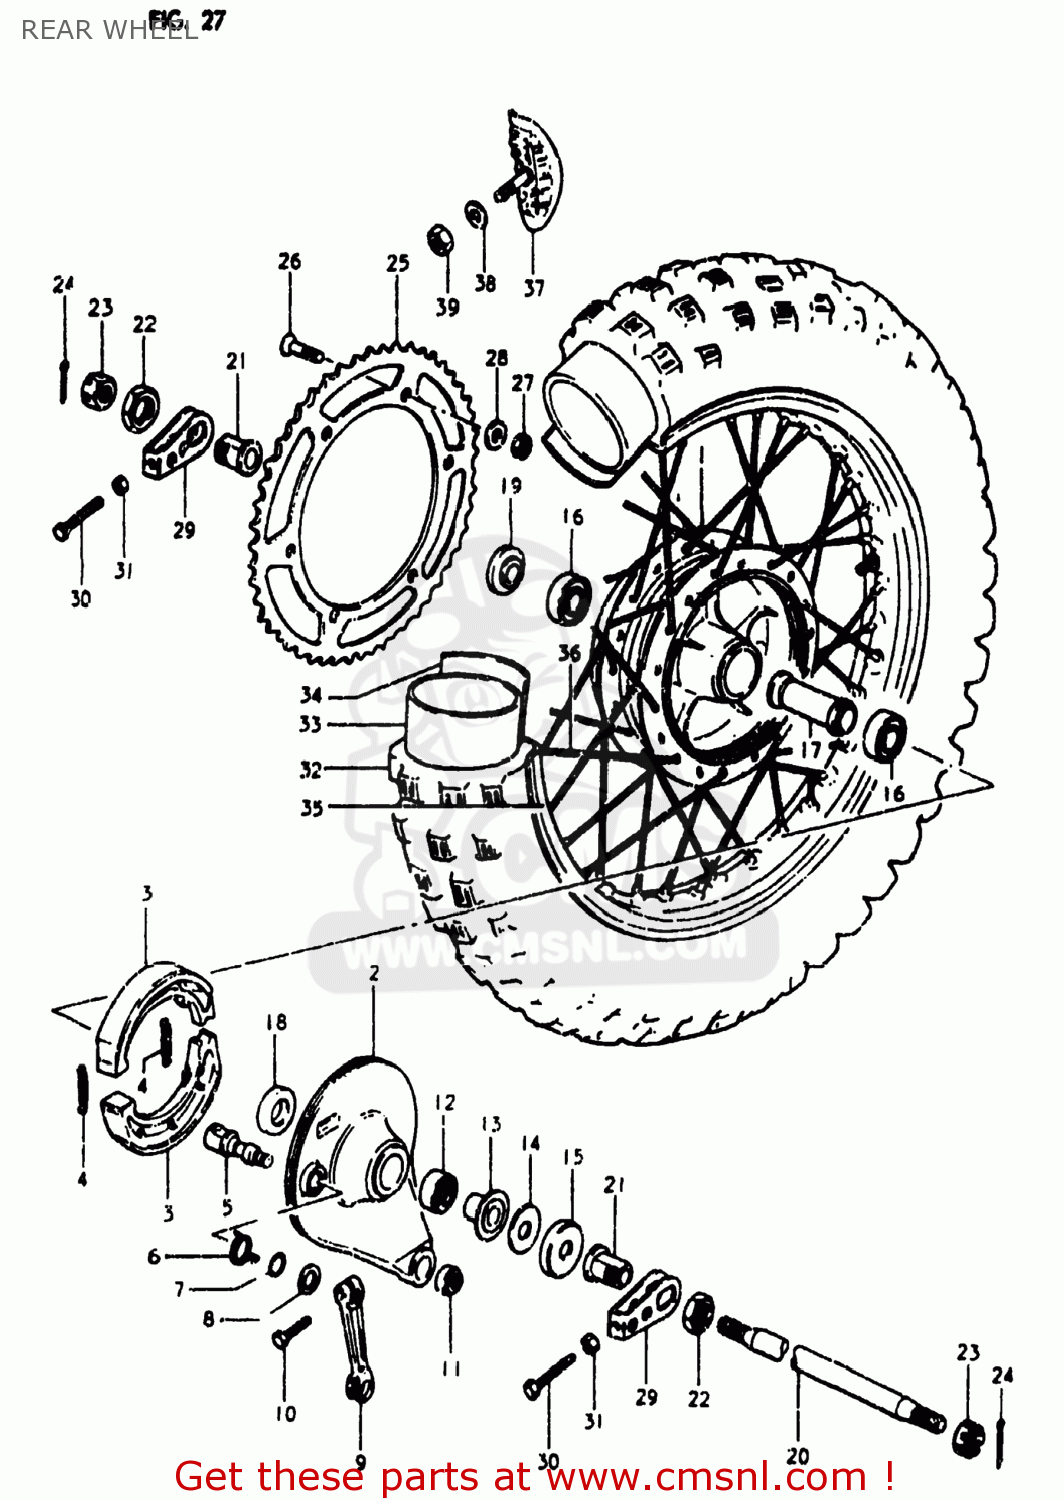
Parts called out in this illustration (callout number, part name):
1	HUB,REAR
2	PANEL SET,REAR HUB
3	SHOE,BRAKE (NAS)
4	SPRING
5	CAM,FR BRAKE
6	SPRING
7	O RING(D:2.5,ID:11.4)
8	WASHER(12.5X20X1)
9	LEVER,REAR BRAKE CAM
10	BOLT
11	SPHERICAL BEARING,TORQUE
12	BEARING(22X29X25)
13	SPACER,REAR HUB PANEL
14	WASHER
15	COVER, PANEL DUST SEAL
16	BEARING
17	SPACER,REAR HUB BEARING
18	SPACER,REAR AXLE,RIGHT
19	SPACER,REAR AXLE,RIGHT
20	AXLE,REAR
21	SPACER,CHAIN ADJUSTER
22	NUT
23	NUT
24	COTTER PIN
25	SPROCKET,REAR
26	SCREW(8X33.5)
27	NUT
28	WASHER
29	ADJUSTER,CHAIN
30	BOLT
31	NUT
32	TIRE
33	TUBE,INNER
34	PROTECTOR,WHEEL,INNER
35	RIM,REAR WHEEL
36	SPOKE SET,REAR WHEEL
37	STOPPER,BEAD
38	WASHER
39	NUT
